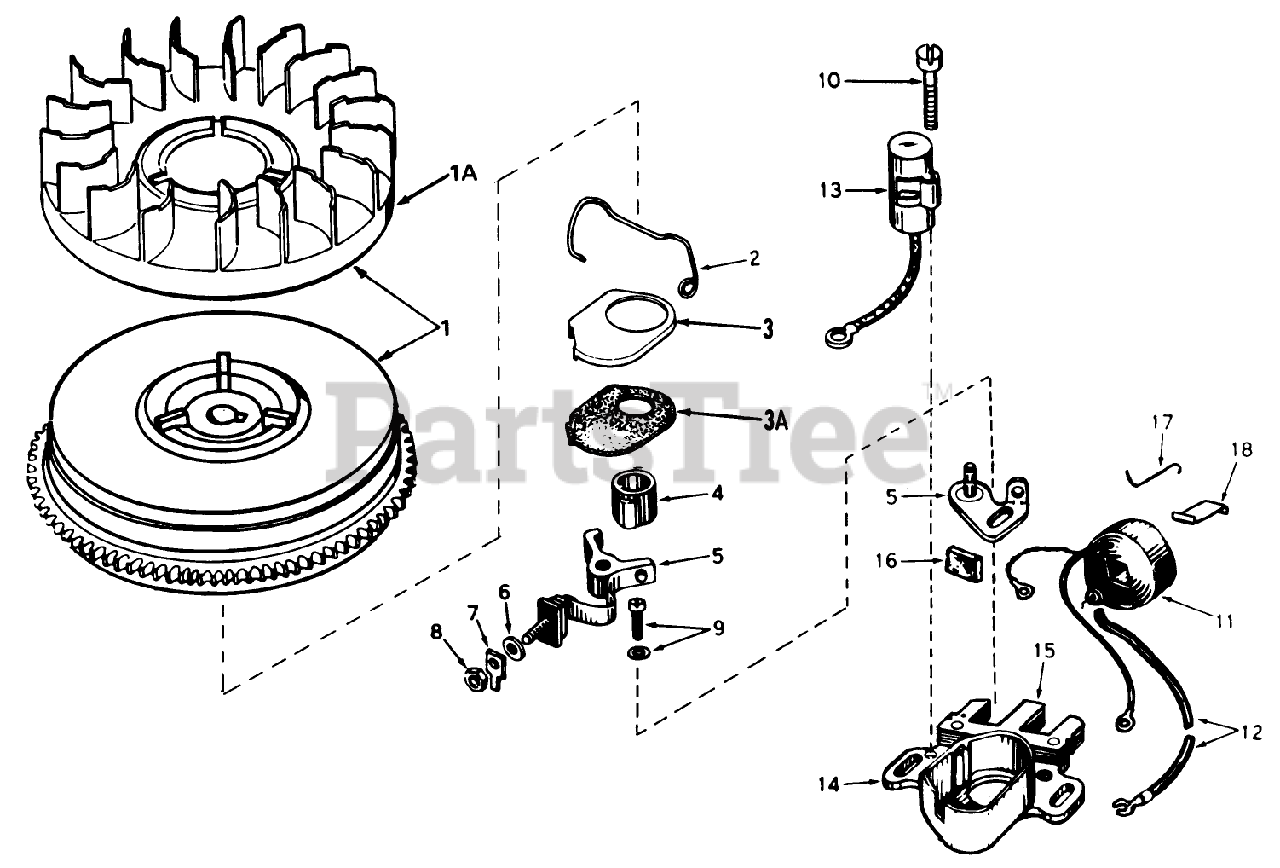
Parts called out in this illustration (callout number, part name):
1	Flywheel (Incl. Nos. 1A, 3 3A)
2	Spring Breaker Box
3	Cover-Dust
3A	Gasket, Dust Cover
4	Cam-Breaker
5	Breaker Assy.
6	Washer
7	Terminal, Ground
8	Nut Terminal
9	Breaker Screw
10	Condenser Screw
11	Coil Assy. (Incl. No. 12)
12	Wire, Lead
13	Condenser
14	Core Plate
15	Stator Assy. (Incl. Ref. #2 thru 11, 13, 14, 16, 17 19)
16	Felt,Cam Wiper
17	Clip, Coil
18	Spring Coil Wedge
